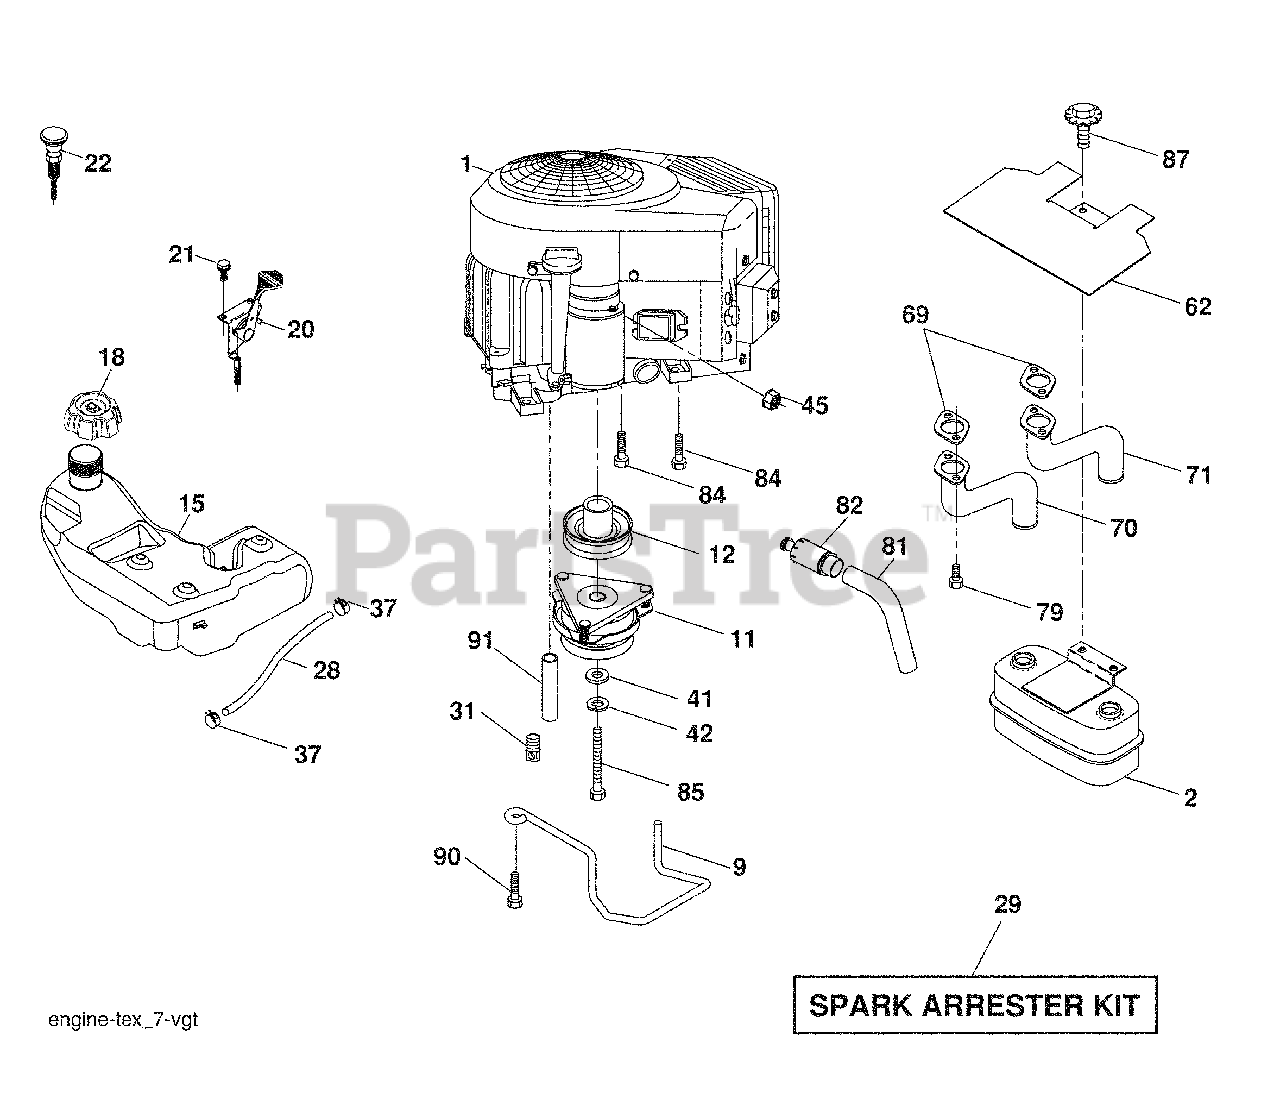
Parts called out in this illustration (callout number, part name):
9	Keeper Belt Engine
11	Clutch Electric
12	Pulley Engine
15	Tank Fuel 4.0
18	Cap Asm
20	Control Throttle
21	Screw #10 x .750 BOS Thread
22	Control Choke
28	Fuel Line
29	Spark Arrester Kit
31	Clip Push-In
37	Clamp Hose
41	Washer 1-1/2 OD x 15/32 ID x .250
42	Washer Lock 7/16
45	Nut Keps Hex 1/4-20 unc
62	Shield Heat Muffler
70	Tube Exhaust LH
71	Tube Exhaust RH
79	Screw Socket Head 5/16-18 x 1
81	Tube Drain Oil Easy
82	Plug Drain Oil
84	Screw 3/8-16 x 1-1/4
85	Bolt Hex 7/16-20 x 3.75 Gr. 5
87	Bolt 5/16-18 unc x 1 w/Sems
90	Screw 3/8-16 x 1
